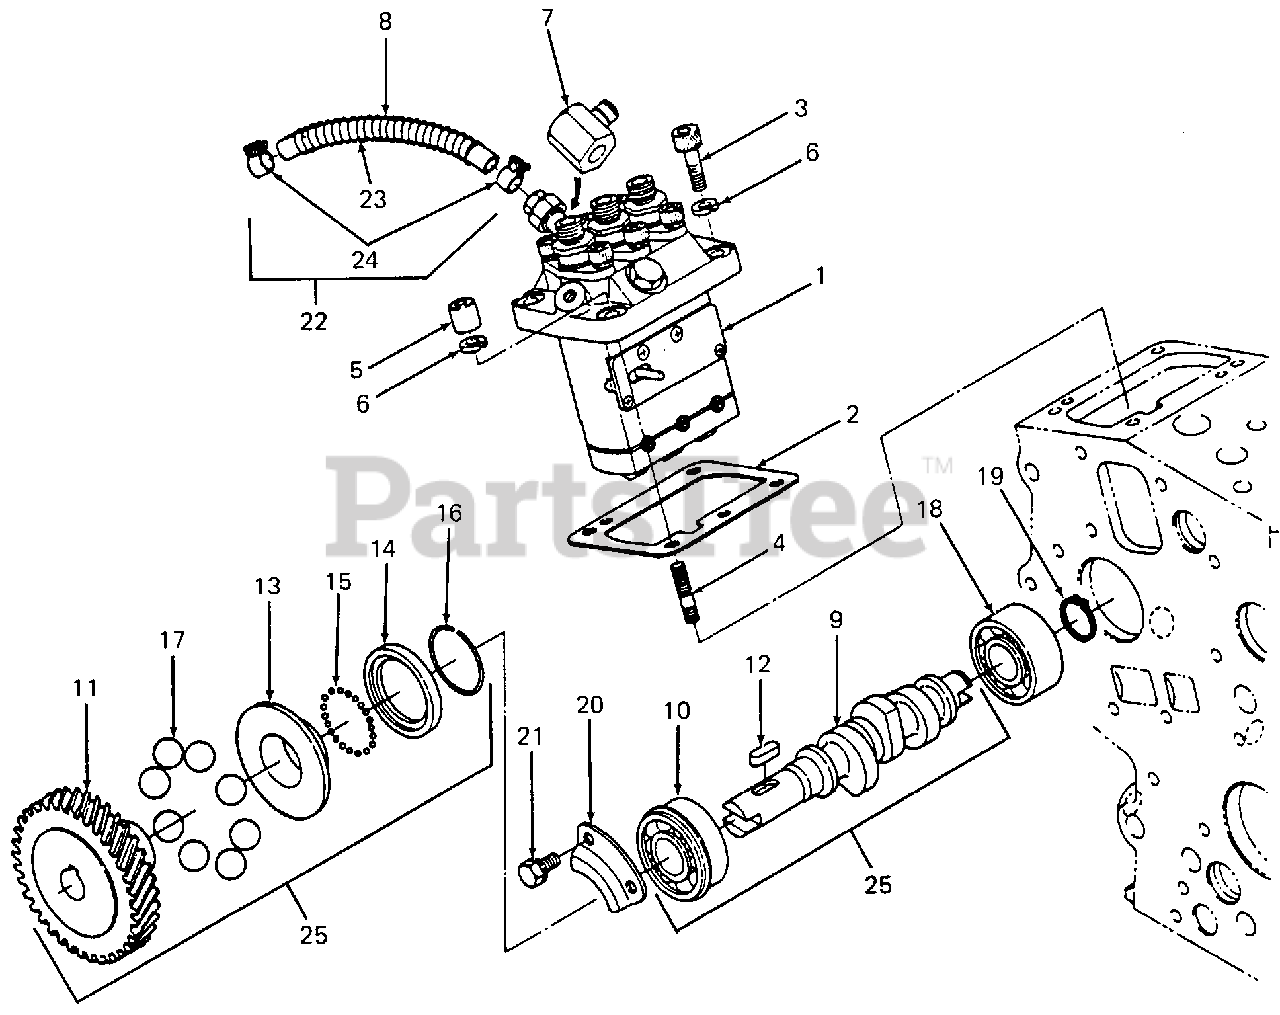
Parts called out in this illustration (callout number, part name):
1	Pump, Injection
2	Shim, Injection Pump
3	Screw, Socket Head
6	Washer, Lock
9	Camshaft, Fuel Injection
10	Bearing, Ball
11	Gear, Injection Pump
13	Sleeve, Governor
14	Case, Governor Ball
15	Ball, Metal, 1/8 Dia
16	Ring, Governor Sleeve Retaining
17	Ball, Metal, 17/32 Dia
18	Bearing, Ball
19	Ring, External Retaining
20	Stop, Fuel Camshaft
21	Screw, Hex Cap w/Washer
22	Pipe Assy, Fuel
24	Clamp, Adjustable Hose
25	Camshaft Assy, Fuel Injection
